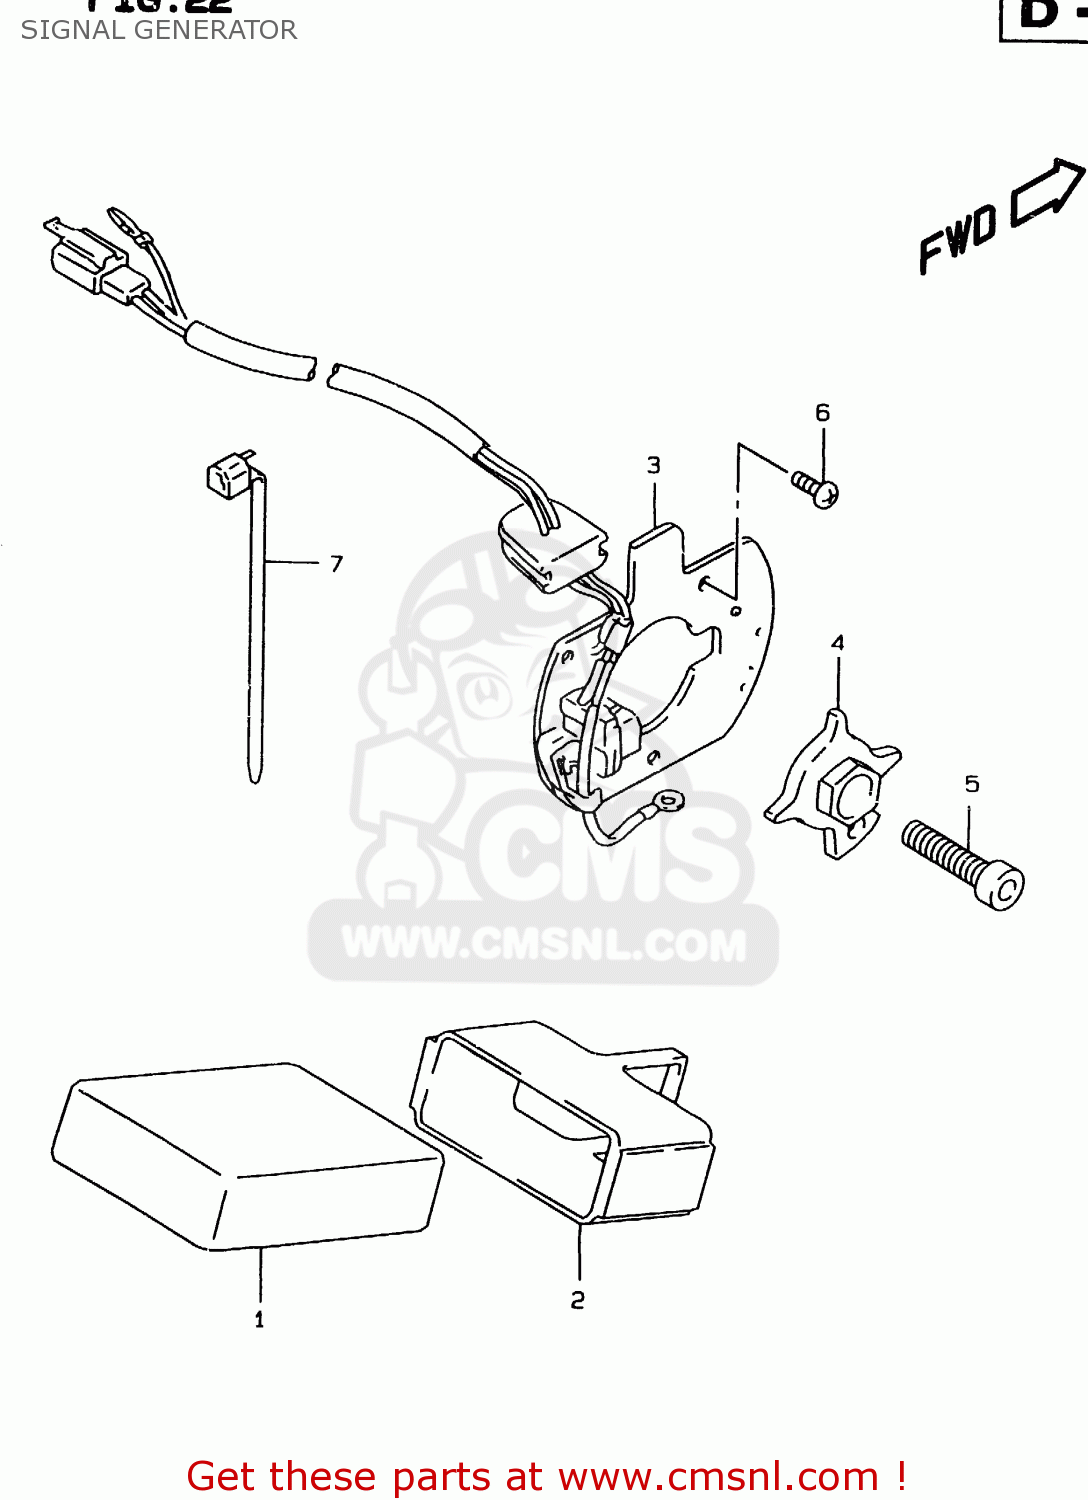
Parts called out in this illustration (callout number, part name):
1	IGNITOR ASSY
2	CUSHION,IGNITOR
3	GENERATOR ASSY,SIGNAL
4	ROTOR,SIGNAL GENERATOR
5	BOLT
6	SCREW
7	CLAMP(L:125)
